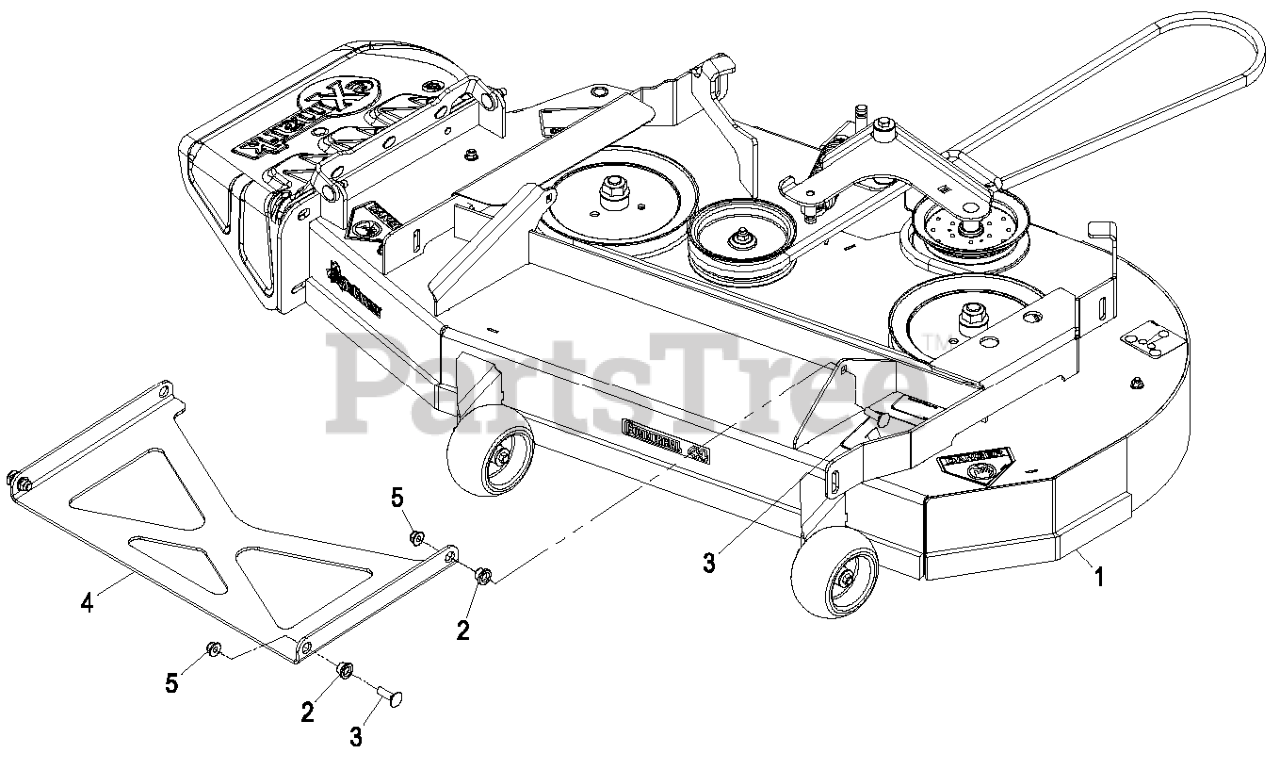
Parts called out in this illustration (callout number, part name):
1	Asm, Complete Deck 44"
2	BUSHING-FLANGED
3	BOLT-CARR
4	STRUT-DECK
5	NUT-HF, NI
